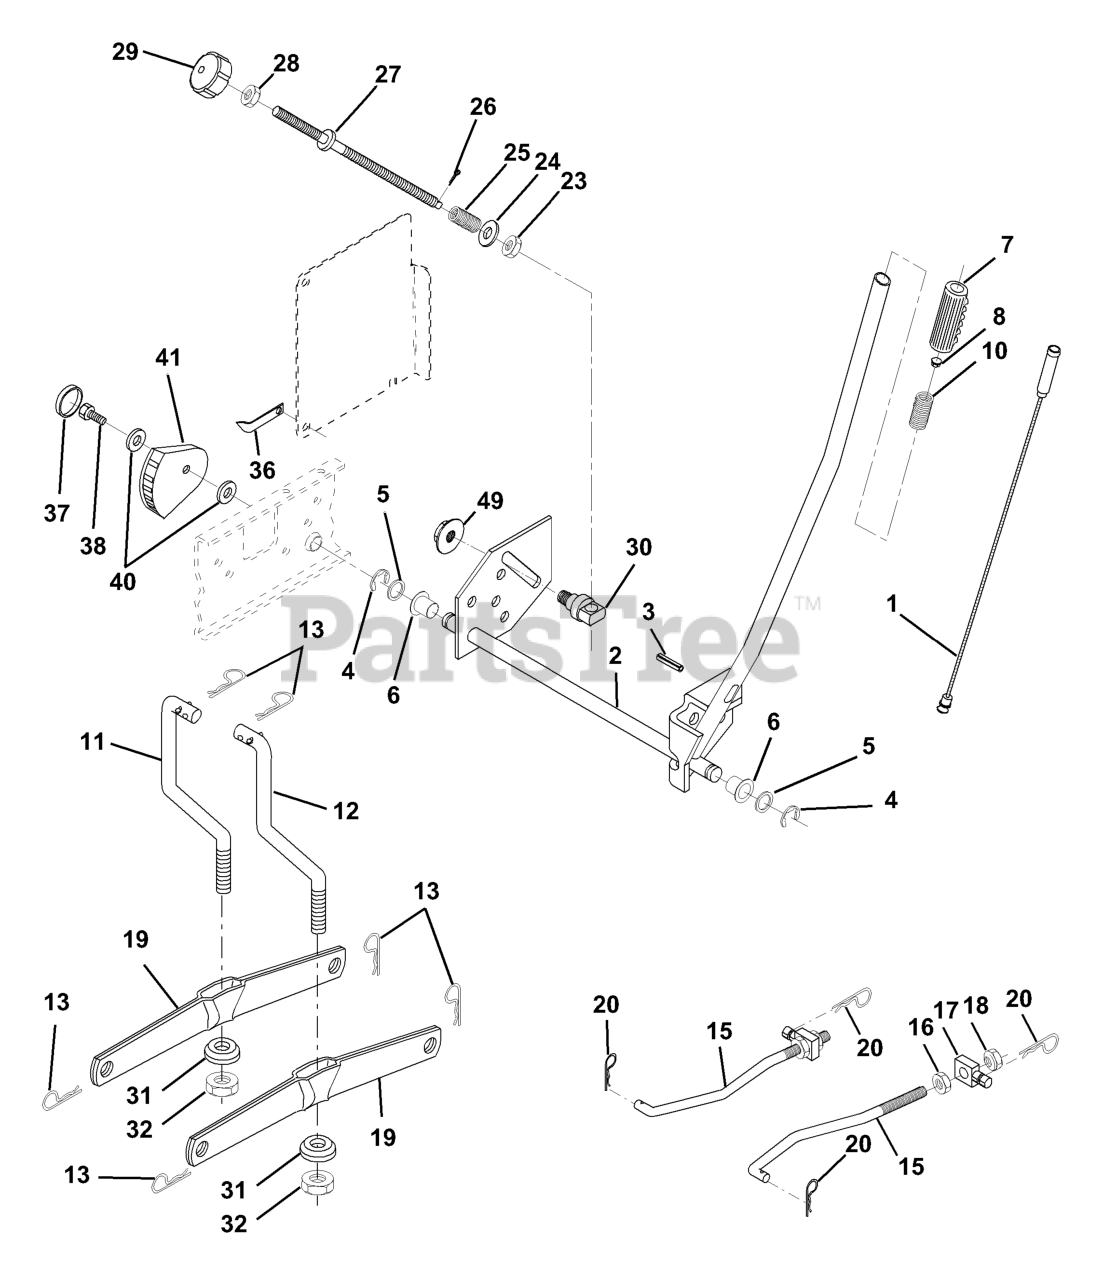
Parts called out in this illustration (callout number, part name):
1	WIRE.INNER.HANDLE.LIFT.LEVER
2	SHAFT ARM LIFT RH
3	PIN GROOVE.
4	RETAINING RING LT
6	BEARING.NYLON
7	GRIP HANDLE
8	PLUNGER BUT KIT
10	SPRING, COMP T
11	LINK LIFT LH
12	LINK LIFT RH
13	RETAINER-SPRNG RB
15	FRONT LINK
16	NUT.HEX.JAM.1/2-13
17	TRUNION
18	NUT.LK.W/WSH.1/2.
19	ARM.REAR.SUSPENSION
20	SPRING RETAINER
25	SPRING**
26	COTTER PIN
27	ROD ADJ LIFT
28	NUT
29	KNOB INF 3/8-16
31	BEARING PIVOT
32	NUT CROWNLOCK 3/8-24
36	POINTER, HEIGHT INDICATOR(2 2)
38	SCREW.THDROL.5/16-18X3/4.TTY
41	IND. HEIGHT STLT
49	NUT
